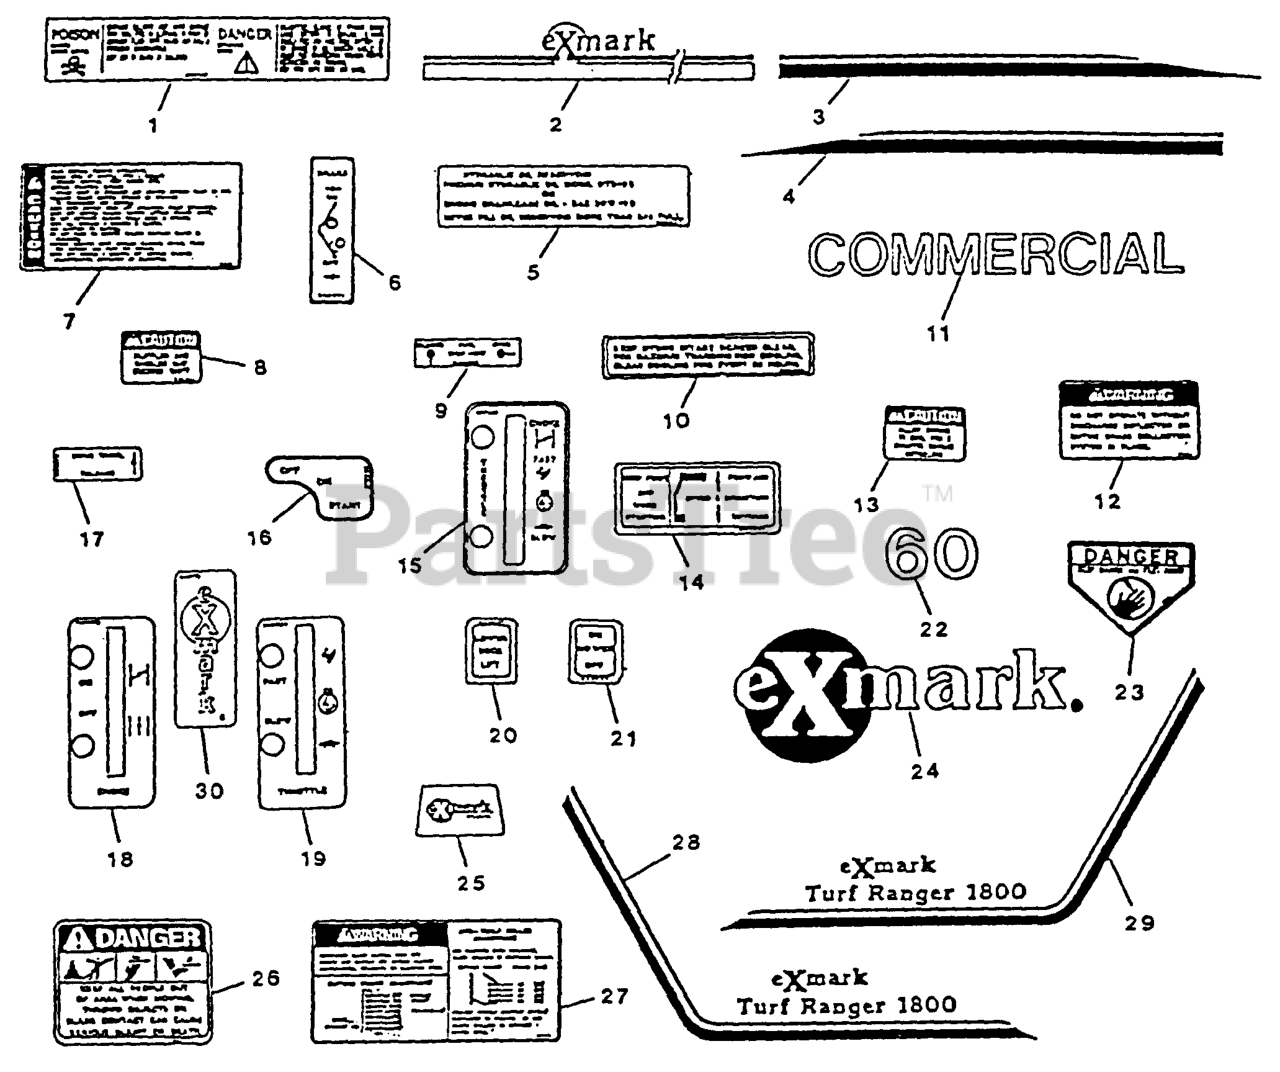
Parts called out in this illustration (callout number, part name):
1	DECAL-BATTERY
14	DECAL,FOOT PEDAL
20	DECAL-DECK LIFT
21	DECAL-MOWER SWITCH
23	DECAL-DANGER
26	DECAL-DANGER
